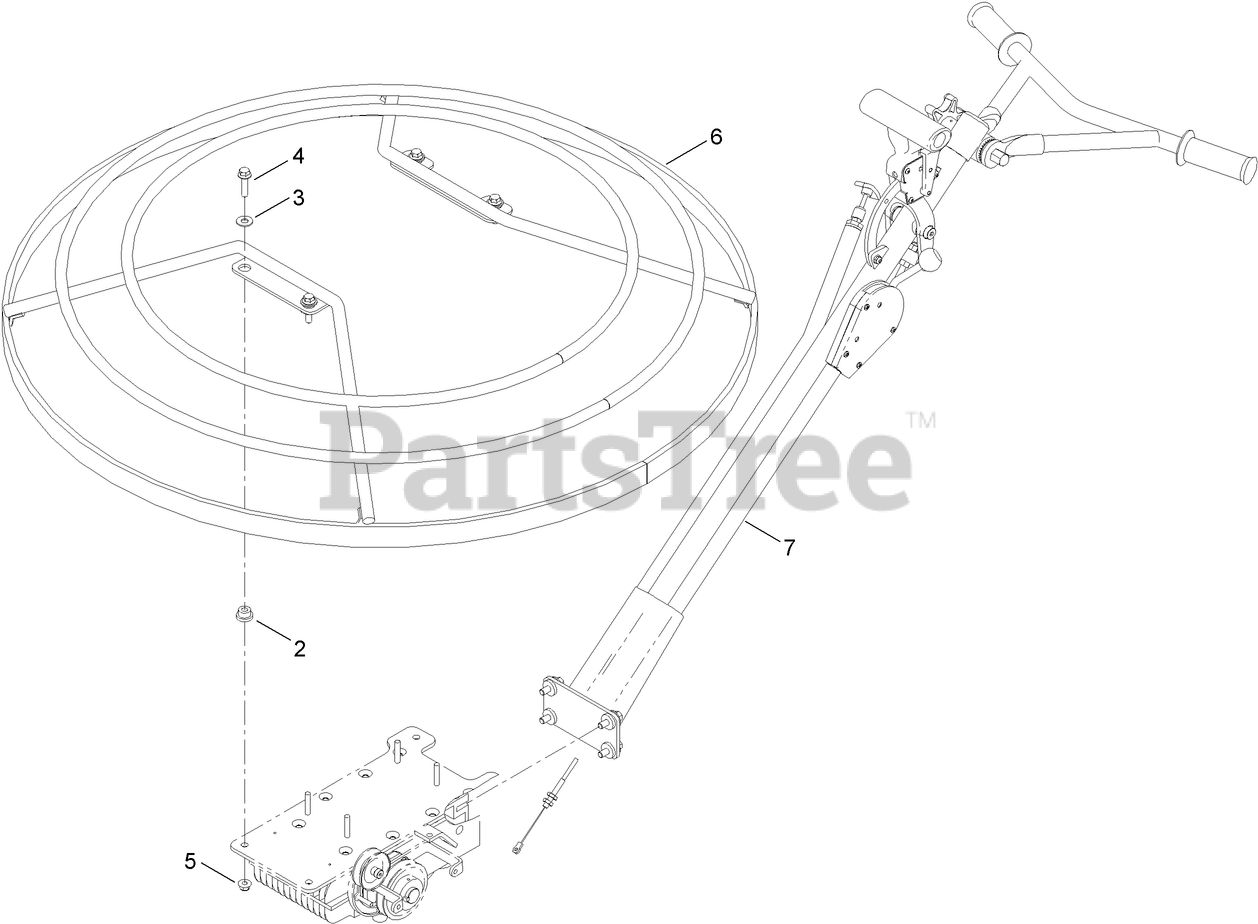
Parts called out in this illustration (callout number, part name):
2	MOUNT-SHOCK
3	WASHER-FLAT
4	SCREW-HHF
5	NUT-HF, NI
6	GUARD-STATIONARY
7	PRO-PITCH HANDLE ASM
